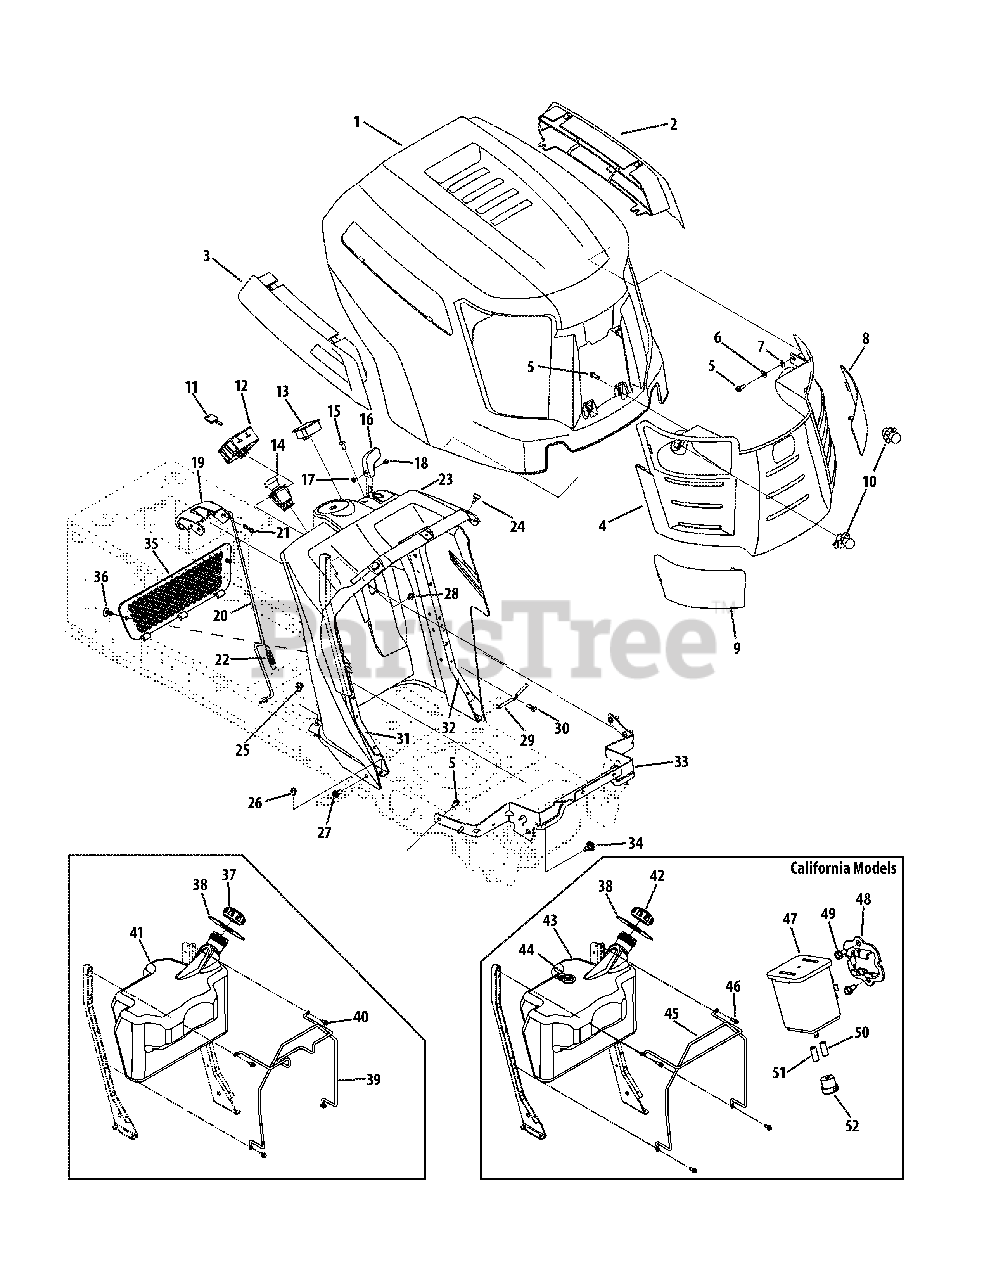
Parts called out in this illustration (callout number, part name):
1	Hood
2	LH Hood Scoop
3	RH Hood Scoop
4	Grille Asm
5	Hex Washer BosScrew™, 1/4 Dia. x .750
6	Flat Washer, .271 x .630 x .065
7	Lock Washer, 1/4
10	Socket, Headlight
11	Key
12	Key Switch
13	Indicator Meter
14	Electric PTO
15	Screw, 1/4-14 x .625
16	Throttle Knob
17	Hex Nut, #8-32
18	Screw, #8-32 x .375
19	Parking Brake/Cruise Control Lever
20	Control Rod
21	Bow-Tie Cotter Pin
22	Extension Spring, .500 x 2.733
23	Dash Panel
25	Hex Washer Screw, 5/16-18 x .750
26	Hex Washer Screw, 1/4-20 x .500
27	Screw, 5/16-18 x .750
28	Hex Washer Screw, 1/4-20 x .625
29	Bent Lever Rod
30	Hex Washer Screw, 1/4-15 x .750
31	Dash Support, RH
32	Dash Support, LH
33	Hood Pivot Bracket
34	Shoulder Screw, 5/16-18 x .43 x .29
36	Ratchet Clip
37	Fuel Cap
38	Fuel Tank Gasket
39	Fuel Tank Support Rod
40	Hex Washer Screw, 1/4-20 x .625
41	Fuel Tank
42	Fuel Cap
43	Fuel Tank
44	Rollover Valve
45	Fuel Tank Support Rod
46	Hex Washer Screw, 1/4-20 x .750
47	Carbon Canister
48	Canister Adapter Bracket
49	Hex Washer Screw, 5/16-18 x .750
50	Fuel Hose, 3/16 White
51	Fuel Hose, 7/32 Yellow
52	Canister Vent Filter
